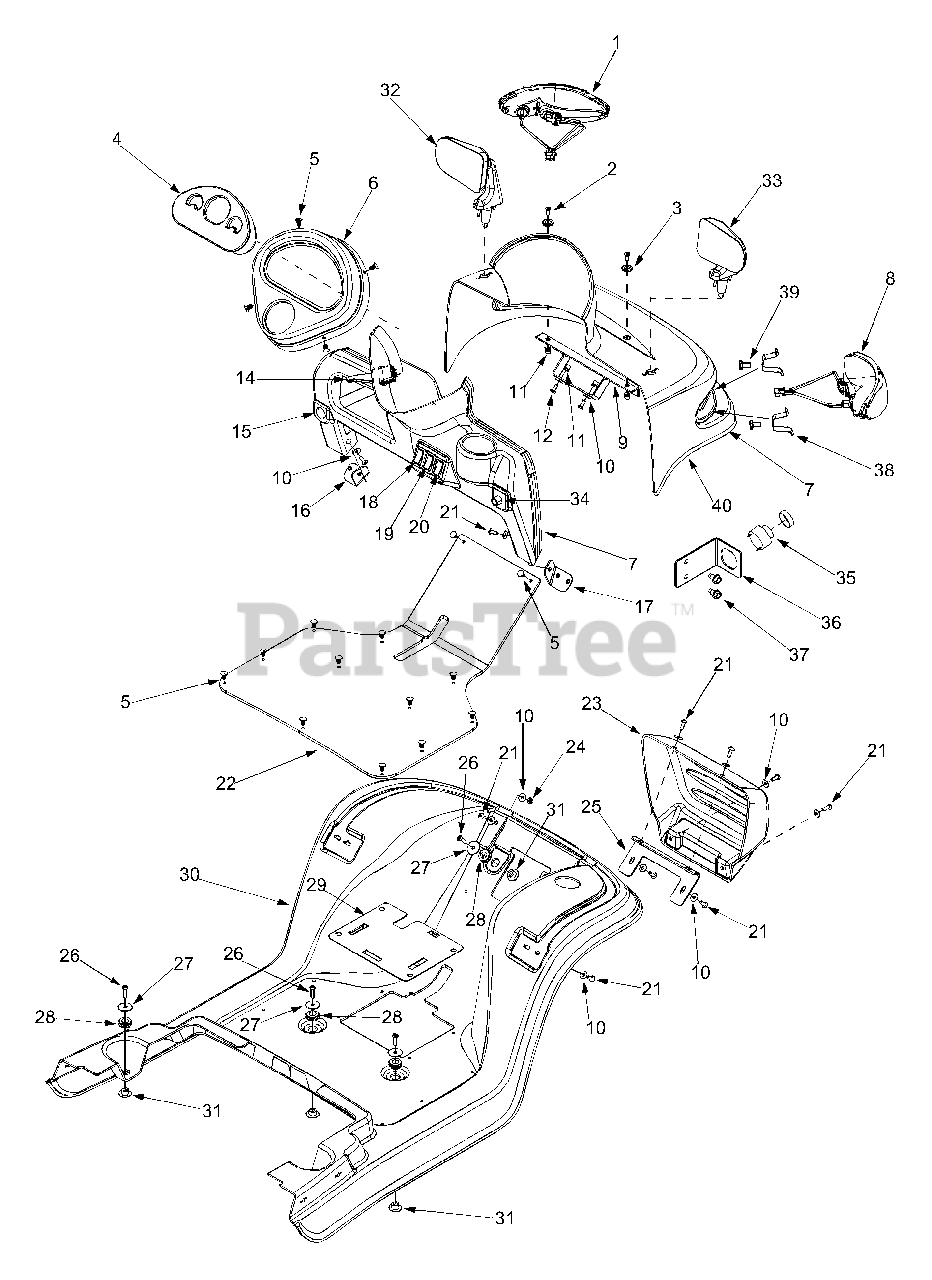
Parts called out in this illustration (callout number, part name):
1	Headlight lamp Assembly - LH
2	Cap Screw 1/4-20 x .750
3	Shoulder Spacer .265 ID x
4	Instruction Panel
5	Retainer Clip
6	Dash Cap Panel
7	Dash Assembly - Silver
8	Headlight Lamp Assembly - RH
9	Upper Dash Support
10	Flat Washer .283 ID x .75 OD
11	Inset Screw 1/4-20
12	Hex Cap Screw 1/4-20 x .620
14	Directional Switch
15	Outlet Power Assembly 12V
16	Lower Dash Support - LH
17	Lower Dash Support - RH
18	Hazard Switch
19	Headlight Switch
20	Horn Switch
21	Screw 1/4-20 x .750
22	Floor Mat
23	Front Bumper Panel
24	Hex Nut 1/4-20
25	Front Bumper Bracket
26	Screw 1/4-20 x 1.0
27	Flat Washer .285 ID x 1.25 OD
28	Rubber Grommet
29	Access Panel
30	Floor Panel - Silver
31	Shoulder Spacer .380 ID x .645 OD
32	Side Mirror - LH
33	Side Mirror - RH
34	Key Switch
36	Horn Bracket
37	Hex Washer Screw 1/4-20 x .500
38	Headlight Clip
39	Hex Cap Screw 1/4-20 x .500
40	Plastic Trim
